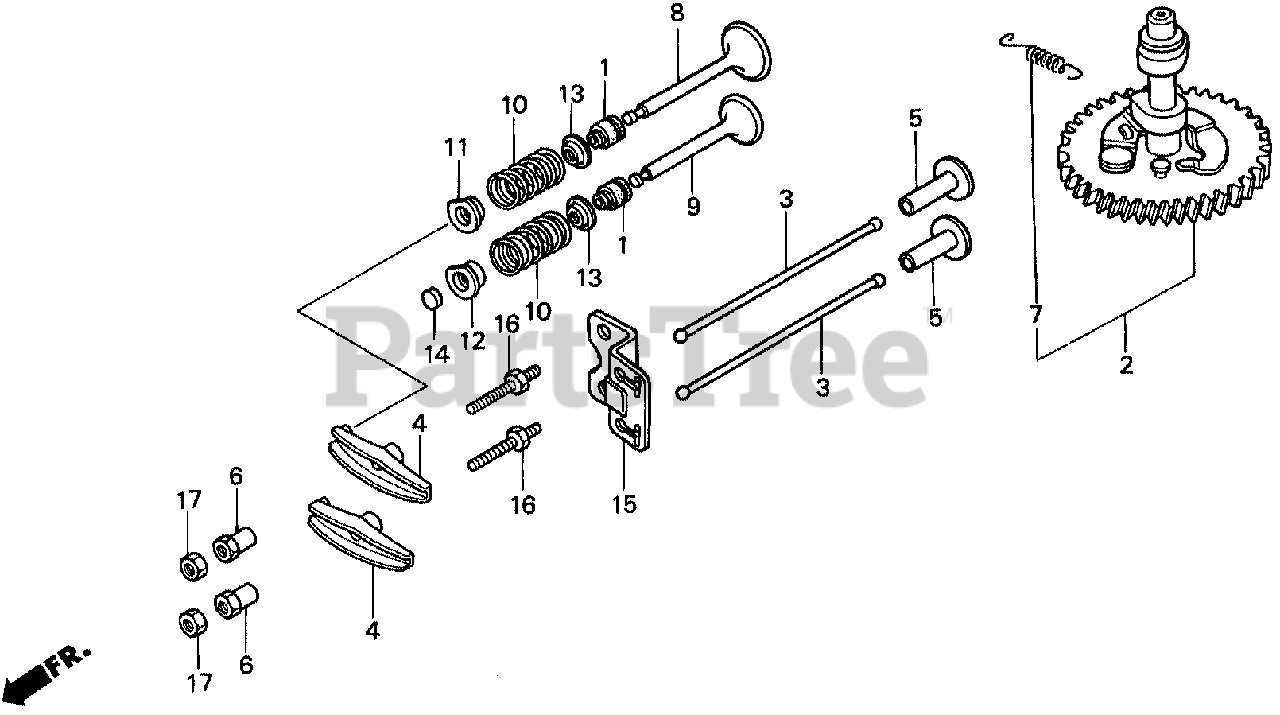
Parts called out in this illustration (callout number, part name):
1	SEAL, VALVE STEM
2	CAMSHAFT ASSY. (NOT AVAILABLE)
2	CAMSHAFT ASSY.
4	ARM, VALVE ROCKER
5	LIFTER, VALVE
6	PIVOT, ROCKER ARM
7	SPRING, WEIGHT RETURN
8	VALVE, IN.
9	VALVE, EX.
10	SPRING, VALVE
11	RETAINER, IN. VALVE SPRING
12	RETAINER, EX. VALVE SPRING
13	SEAT, VALVE SPRING
14	ROTATOR, VALVE
15	GUIDE, PUSH ROD
16	BOLT, PIVOT (8MM)
17	NUT, PIVOT ADJUSTING
